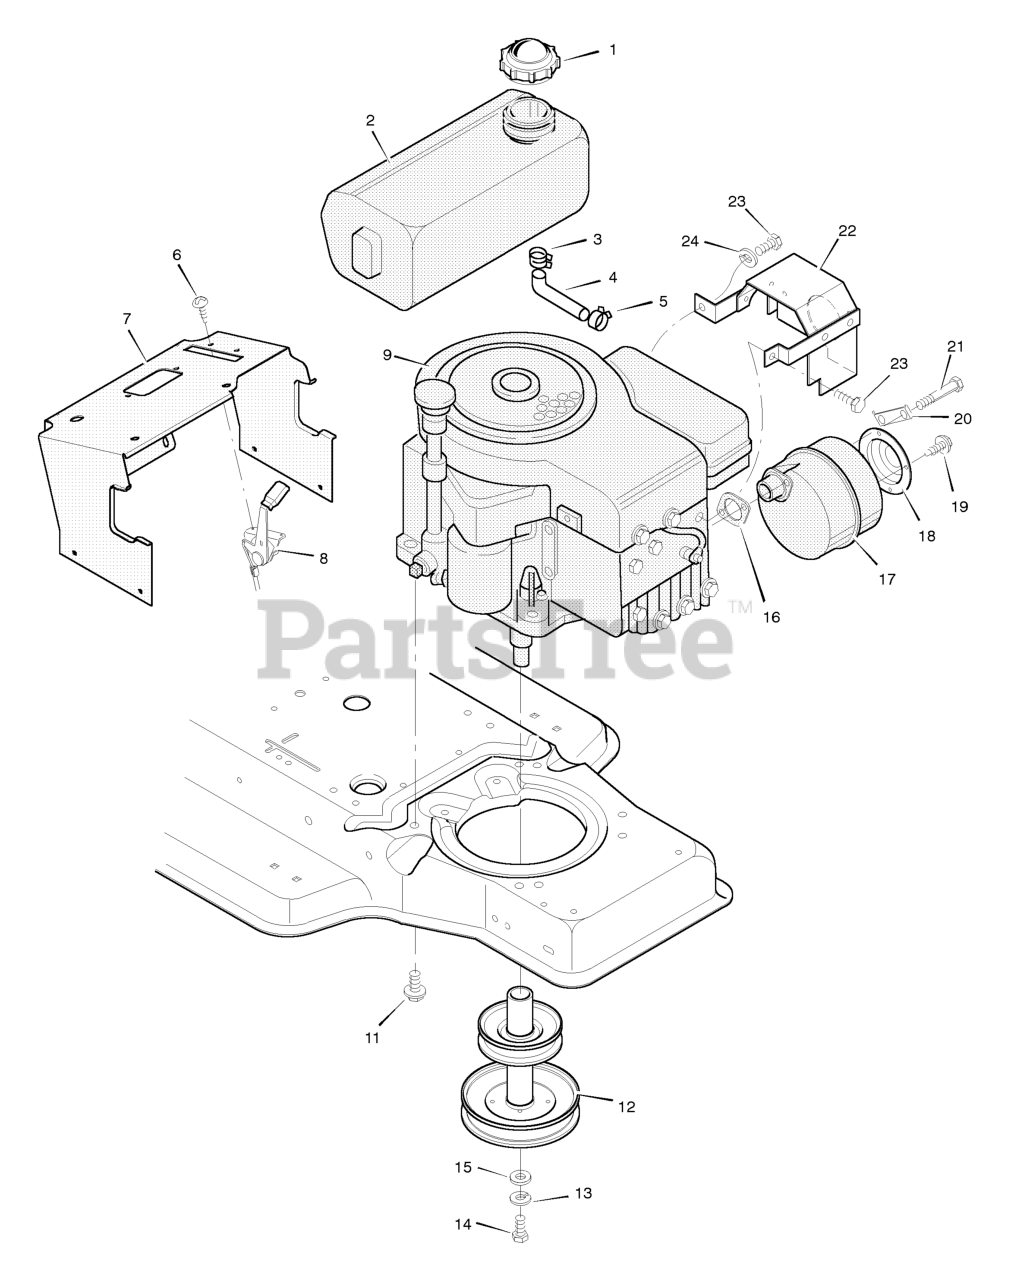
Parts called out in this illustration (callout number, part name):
1	Fuel Cap
2	Fuel Tank
3	Hose Clamp
4	Fuel Line
5	Hose Clamp
7	Support, Dash
8	Throttle Control
9	Engine *
11	Bolt, Engine Mount
12	Stack Pulley Assembly
13	Lockwasher
14	Bolt, Hex
16	GASKET, Exhaust
17	Muffler
18	Deflector, Muffler
20	Lock, Screw
22	Shield, Heat
23	Bolt
